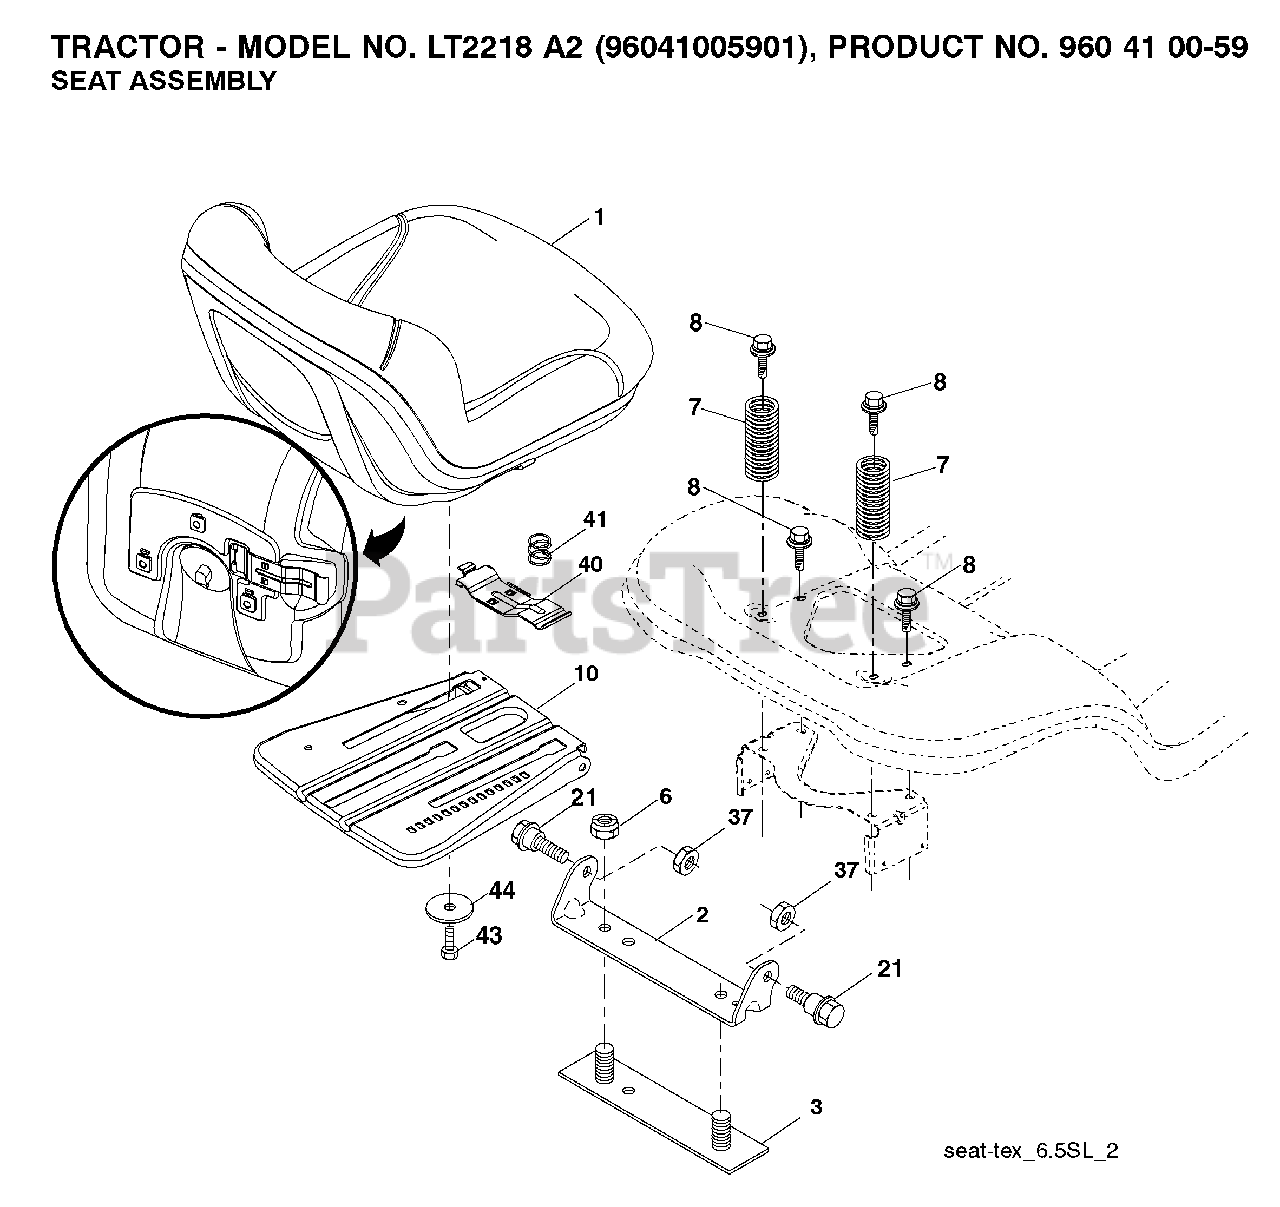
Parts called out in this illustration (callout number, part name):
1	SEAT.TG150.BLK.NLOGO.
2	BRKT.PIVOT.FENDER
6	NUT
7	SPRING COMPRESSION
8	BOLT, 5/16-18 X 1 3/4
10	PAN.ASM.SEAT.3PT
21	BOLT.SHOULDER.5/16-18
37	NUT.71038.31-18.HEX.NYLOCK
40	HANDLE.SLIDE.SEAT.TEX.BLACK
41	SPRING.LATCH.SEAT.TEX
44	WASHER 13/32 X 2-3/8 X 12GA
